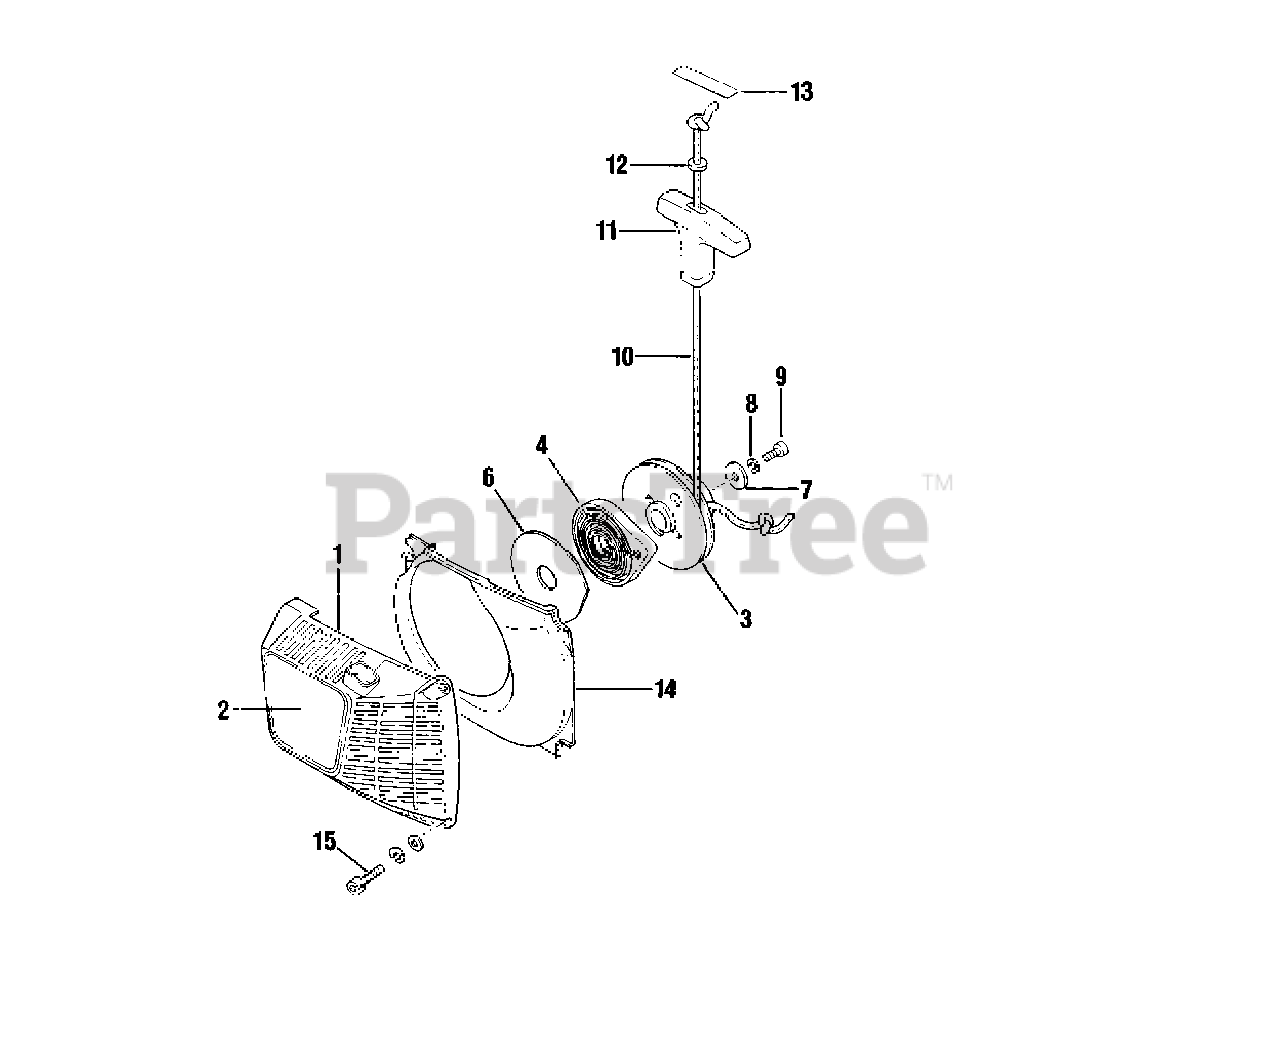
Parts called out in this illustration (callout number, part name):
1	CASE, STARTER
2	NAME PLATE
3	REEL
4	RECOIL SPRING W/CASE
6	SLIDE PLATE
8	WASHER, SPRING 5
9	BOLT 5×12
10	ROPE
11	RECOIL, KNOB
12	KNOB, STOPPER
13	TAPE
14	DEFLECTOR, AIR
15	BOLT 5×20
16	WASHER, SPRING 5
17	WASHER, FLAT 5.5×10×0.8
